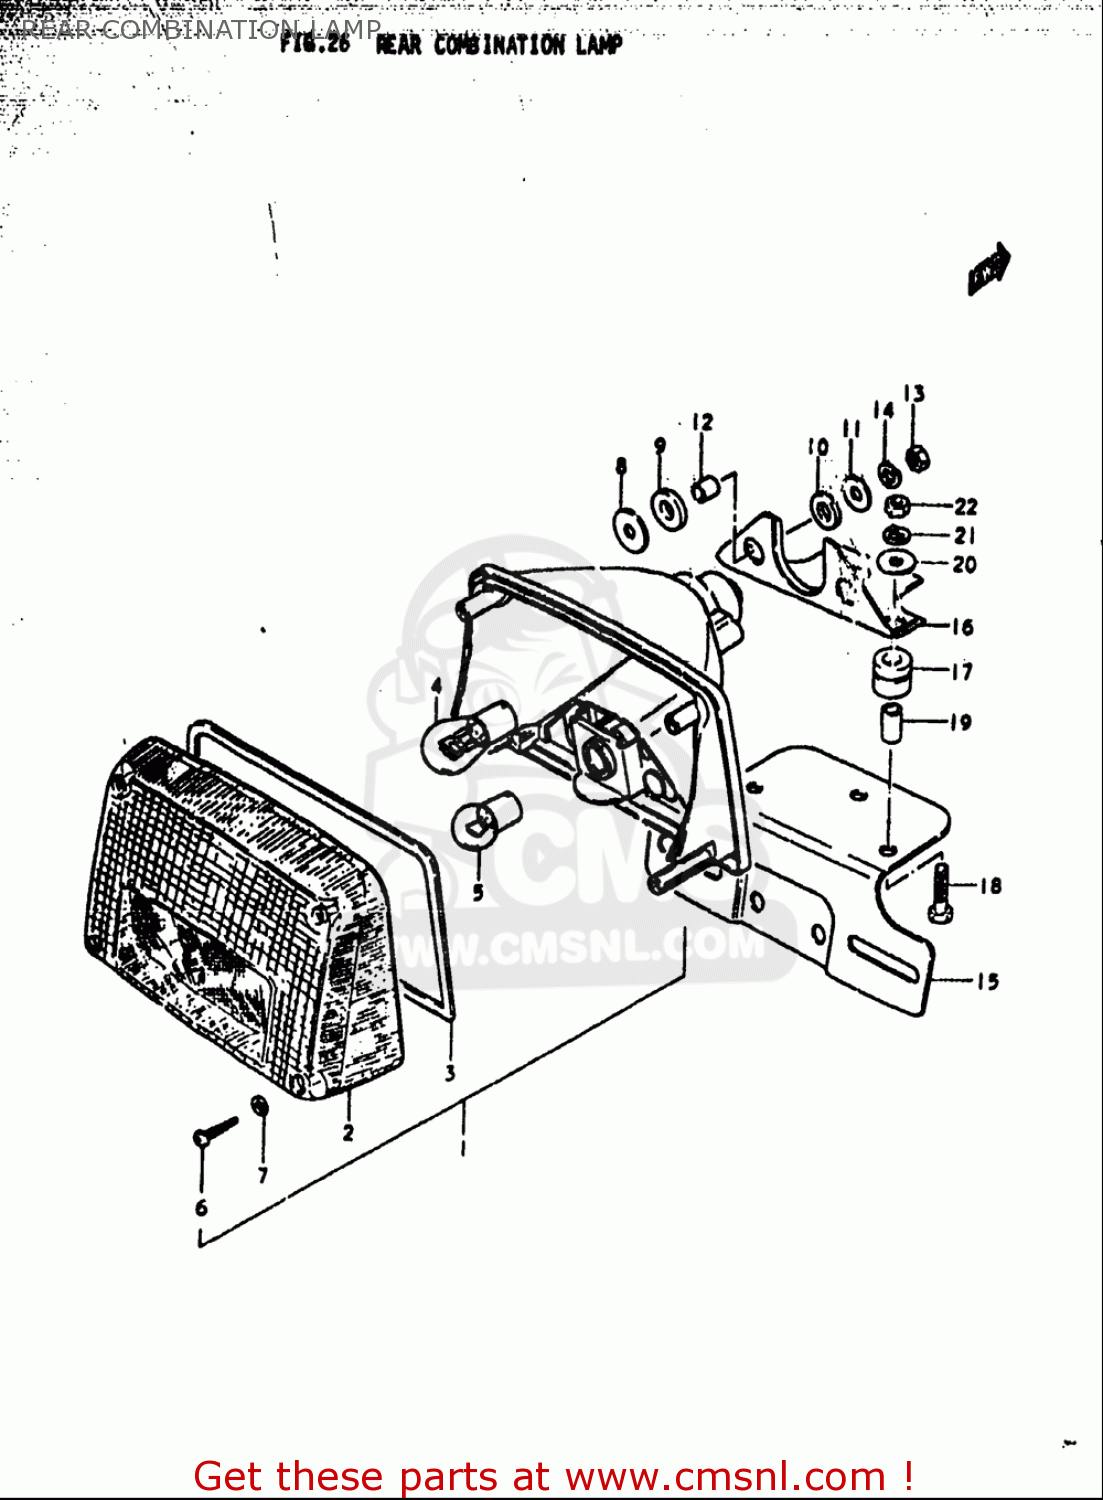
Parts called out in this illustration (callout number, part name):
1	LAMP ASSEMBLY,REAR COMBINATION
2	LENS
3	GASKET (NAS)
4	BULB(12V23W)
5	BULB(12V8W)
6	SCREW
7	GASKET (NAS)
8	WASHER(6.5X18X1.6)
9	CUSHION
10	CUSHION
11	WASHER(6.5X24X1.6)
12	SPACER(6.1X9X7.5)
13	NUT
14	WASHER,LOCK
17	CUSHION
18	BOLT
19	SPACER(6.1X8X15.5)
20	WASHER(6.5X18X1.6)
21	WASHER,LOCK
22	NUT
